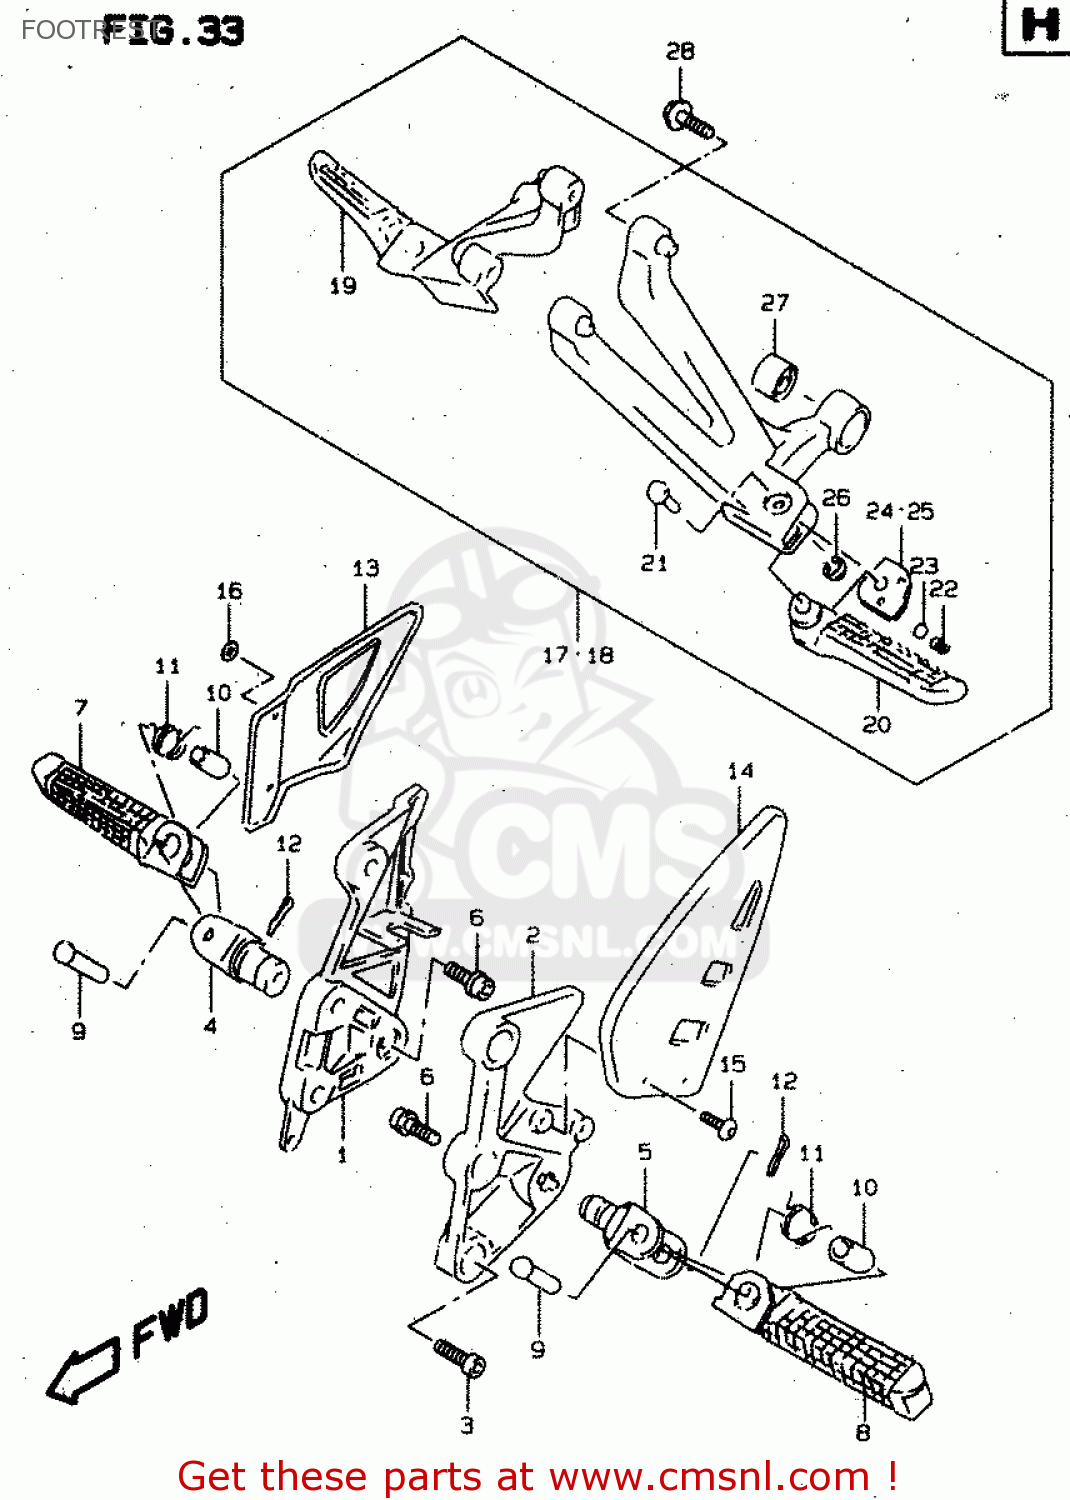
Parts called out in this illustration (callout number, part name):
1	BRACKET,FR FOOTREST,R
2	BRACKET,FR FOOTREST,L
3	BOLT
4	HOLDER,FOOTREST,R
5	HOLDER,FOOTREST,L
6	BOLT(10X28)
7	BAR,FRONT FOOTREST,RIGHT
8	BAR,FRONT FOOTREST,LEFT
9	PIN
10	SPACER(8.1X12X22)
11	SPRING
12	PIN 20X15
13	GUARD,FR FOOTREST,R
14	GUARD,FR FOOTREST,L
15	SCREW(5X10)
16	WASHER(6.5X16X1)
17	FOOTREST ASSY,PILLION,R
18	FOOTREST ASSY,PILLION,L
19	BAR,PILLION FOOTREST,RIGHT
20	BAR,PILLION FOOTREST,LEFT
21	PIN
22	SPRING
23	BALL
24	PLATE,PILLION,RIGHT
25	PLATE,PILLION,LEFT
26	E-RING
27	BUSH
28	BOLT
